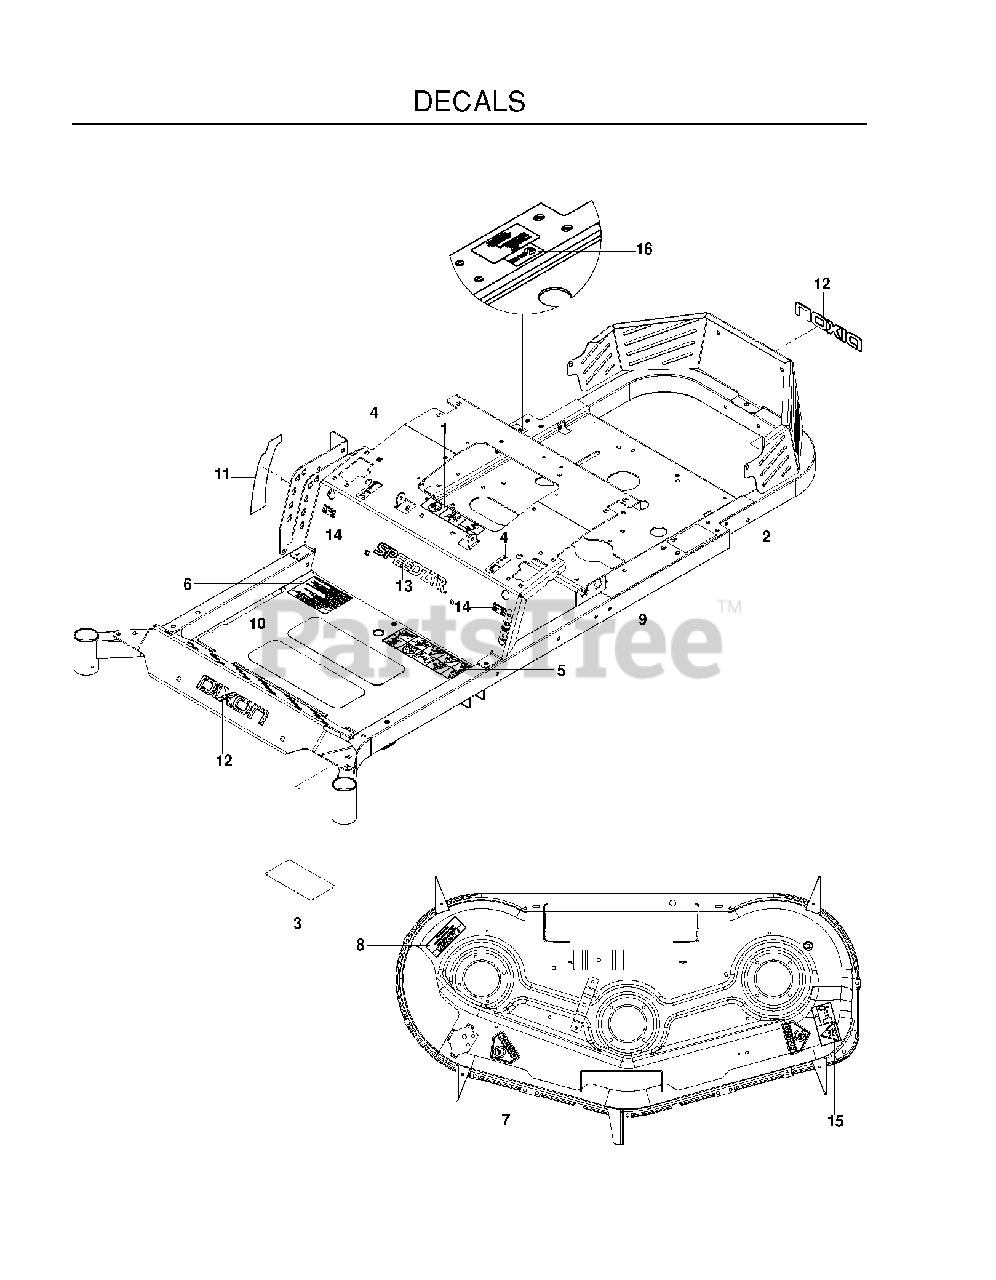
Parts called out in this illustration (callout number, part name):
1	DECAL, BATTERY
2	DECAL, DO NOT MOUNT
3	DECAL, SERVICE
4	DECAL, MOTION CONTROL
5	DECAL, WARNING
6	DECAL, WARNING
7	DECAL, CPSC
8	DECAL, DANGER
9	DECAL, PARK BRAKE
10	ANTI-SKID PAD
11	DECAL, HEIGHT
12	DECAL, DIXON LOGO, DOMED
13	DECAL, SPEEDZTR, 8"
14	DECAL, F.S.T.
15	DECAL, EURO SEVERING
16	DECAL, ECM, AUSTRALIA
